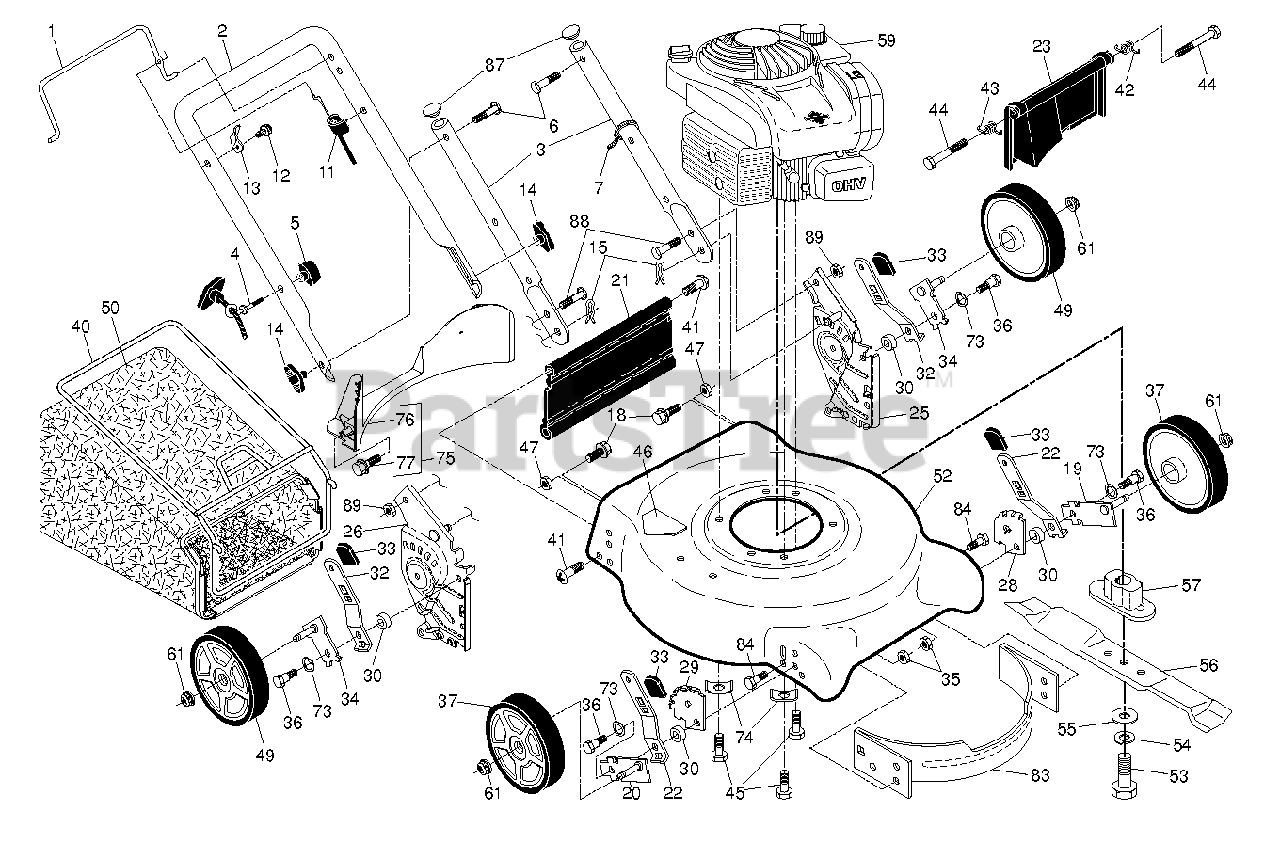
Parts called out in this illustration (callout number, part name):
1	BAIL.CONT.D.STRAIGHT.PUSH.BLK
2	HANDLE.UPPER.ECONOMY.BLACK
3	HANDLE.LOWER.DOME.BT.BLACK
4	Rope Guide, Blk Zinc Chrom
5	T-KNOB.NEW ROPE GUIDE
6	BOLT, HANDLE 5/16-18X1.75
7	TIE GUIDE
11	CABLE.MZR.RATO.22"LOW.
13	BRACKET.UPSTOP.RT
15	HAIRPIN COTTER
18	SCREW 1/4X20
19	AXLE ARM ASSY FRONT LH
20	AXLE ARM ASSY FRONT RH
21	KIT.SKIRT.21 DOMED.W/LIP
22	SELECTOR SPRING, FRONT
23	REAR DOOR ASSY
25	BRACKET.ASM.HAND.LW.21.RT.BLAC
26	BRACKET.ASM.HAND.LW.21.LT.BLAC
28	BRACKET.ADJ.5.RTAB.LG.HOLE.ABS
29	BRACKET.ADJ.5.LTAB.LG.HOLE.ABS
30	SPACER.HEIGHT.ADJUSTER
32	SPRING.SELECTOR.21RD.HTTRT.BZP
34	ARM.ASM.AXLE.REAR.5/9.POS.BZP
35	NUT.FLANGE.HEX.5/16X18.BLACK
36	SHOULDER BOLT 5/16-18
37	WHEEL.7X1.75.5SPK.BRK.BLACK
40	FRAME.BAG.21.REAR.DOMED.PUSH
41	SCREW.1/4-20X21/4.HEX.
42	SPRING.LH.22.REAR.DOOR.EZ.EMPT
43	SPRING.RH.22.REAR.DOOR.EZ.
45	BOLT 3/8-16X1-1/8
46	No Step Decal
47	NUT.71038.31-18.HEX.NYLOCK
49	WHEEL.8X1.75.5.SPK.BRK.BLK.1
50	GBAG.24710612.BLK.WEAT
52	HOUSING.21RD.DOME.GRE
53	WASHER,HARDEN
55	WASHER,HARDEN
56	BLADE.21.PUSH/RWGD/FWGD
57	ADAPTOR.BLADE.7/8
61	NUT.HEX.FLANGE.3/8-16.LOCKNUT
73	WASHER.CURVED.CYLINDRICAL
74	WASHER.ENGINE.BZP
76	BAFFLE.REAR.PLASTIC.21.RD.ECON
77	SCREW.HX.13X.750
83	BAFFLE.FRONT.21.DOME.US
84	BOLT.5/16HEX.WHS.HD
87	PLUG.PLASTIC.7/8".14-20.GAUGE
89	LOCKNUT-FLANGE 5/16-18
